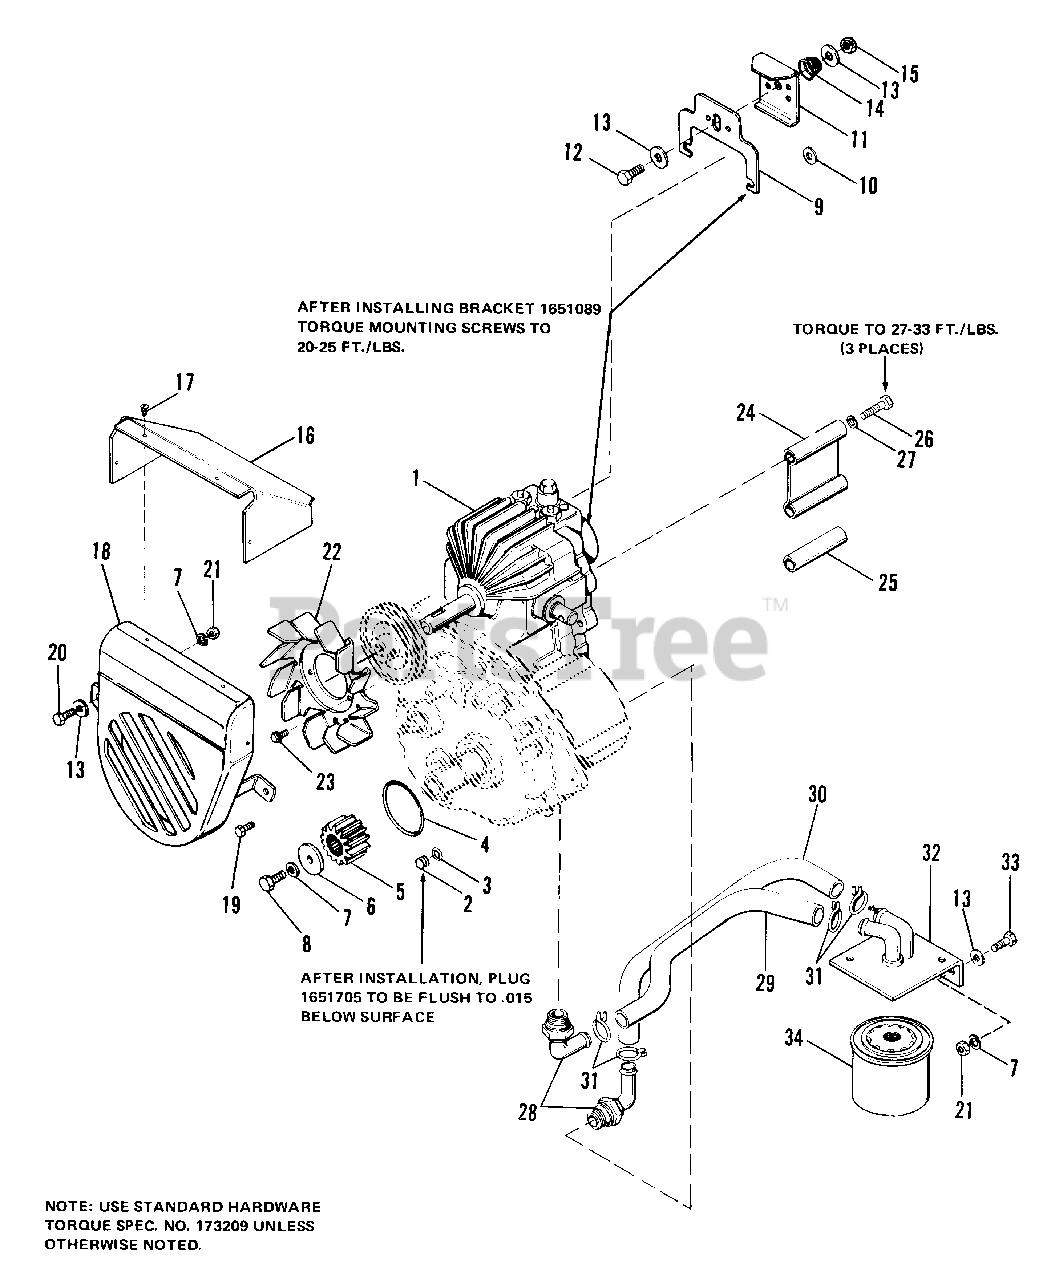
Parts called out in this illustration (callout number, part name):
1	HYDRO PUMP & MOTOR UNIT
5	PINION, Motor Shaft
7	LOCKWASHER, 5/16
8	CAPSCREW, Hex Hd., 5/16-18 x 3/4
11	RELEASE, Latch
12	CAPSCREW, Hex Hd., 5/16-18 x 1
13	WASHER, 5/16
15	LOCKNUT, Hex, 5/16-18
16	DEFLECTOR, Shroud
17	SCREW, Taptite No. 10-32 x 3/8
18	SHROUD ASSY, Fan
19	SCREW, Thd Form., 5/16-18 x 1/2
20	CAPSCREW, Hex Hd., 5/16-18 x 3/4
21	NUT, Hex Full, 5/16-18
22	FAN, Pulley
23	SCREW, Thd., Form., 1/4-20 x 3/8
25	SPACER
26	CAPSCREW, Hex Hd., 3/8-16 x 5
27	LOCKWASHER, 3/8
28	INSERT, Hose
31	CLAMP, Hose
32	SUPPORT ASSY, Oil Filter
33	CAPSCREW, Hex Hd., 5/16-18 x 7/8
34	FILTER ASSY
